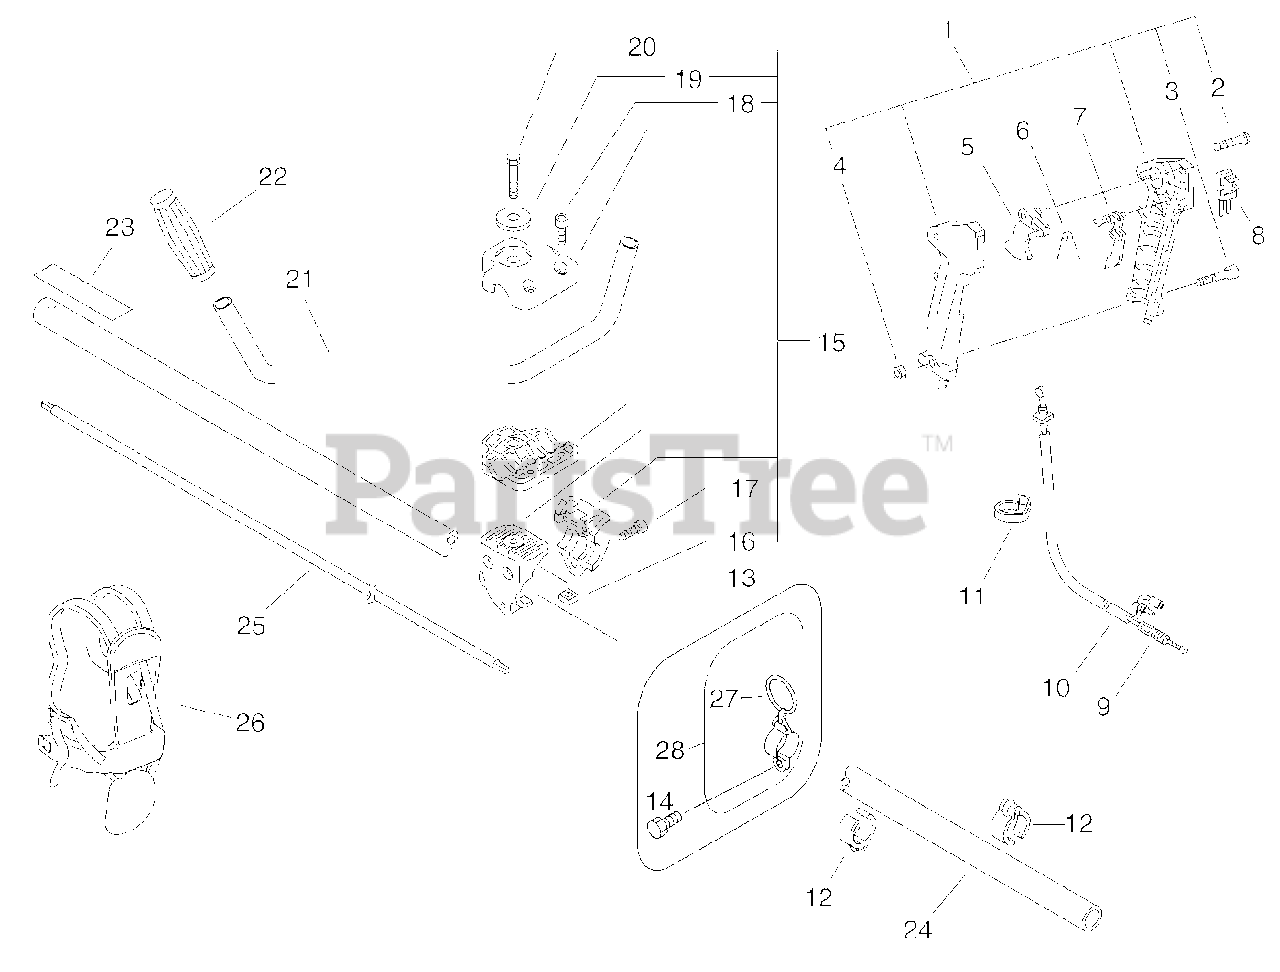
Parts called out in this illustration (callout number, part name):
1	CONTROL HANDLE KIT
2	SCREW 3×25
3	SCREW 5×30
4	NUT M5
5	TRIGGER, THROTTLE
6	SPRING, TORSION
7	LOCKOUT, THROTTLE
8	SWITCH, ON-OFF
9	CABLE, THROTTLE
10	TUBE, FLEXIBLE 7×790
12	CLIP, CABLE 25 MM
13	HANGER ASSY
14	BOLT 5×12
15	BRACKET ASSY, HANDLE
16	NUT 8×1.25
17	BOLT 5×30
18	BOLT 5×20
19	WASHER 8
20	BOLT 8×55
21	HANDLEBAR
22	GRIP, HANDLE
23	LABEL, CAUTION - ISO
24	MAIN PIPE ASSY 25×L= 1500
25	DRIVESHAFT
27	RING, HARNESS
28	HANGER ASSY, HARNESS
